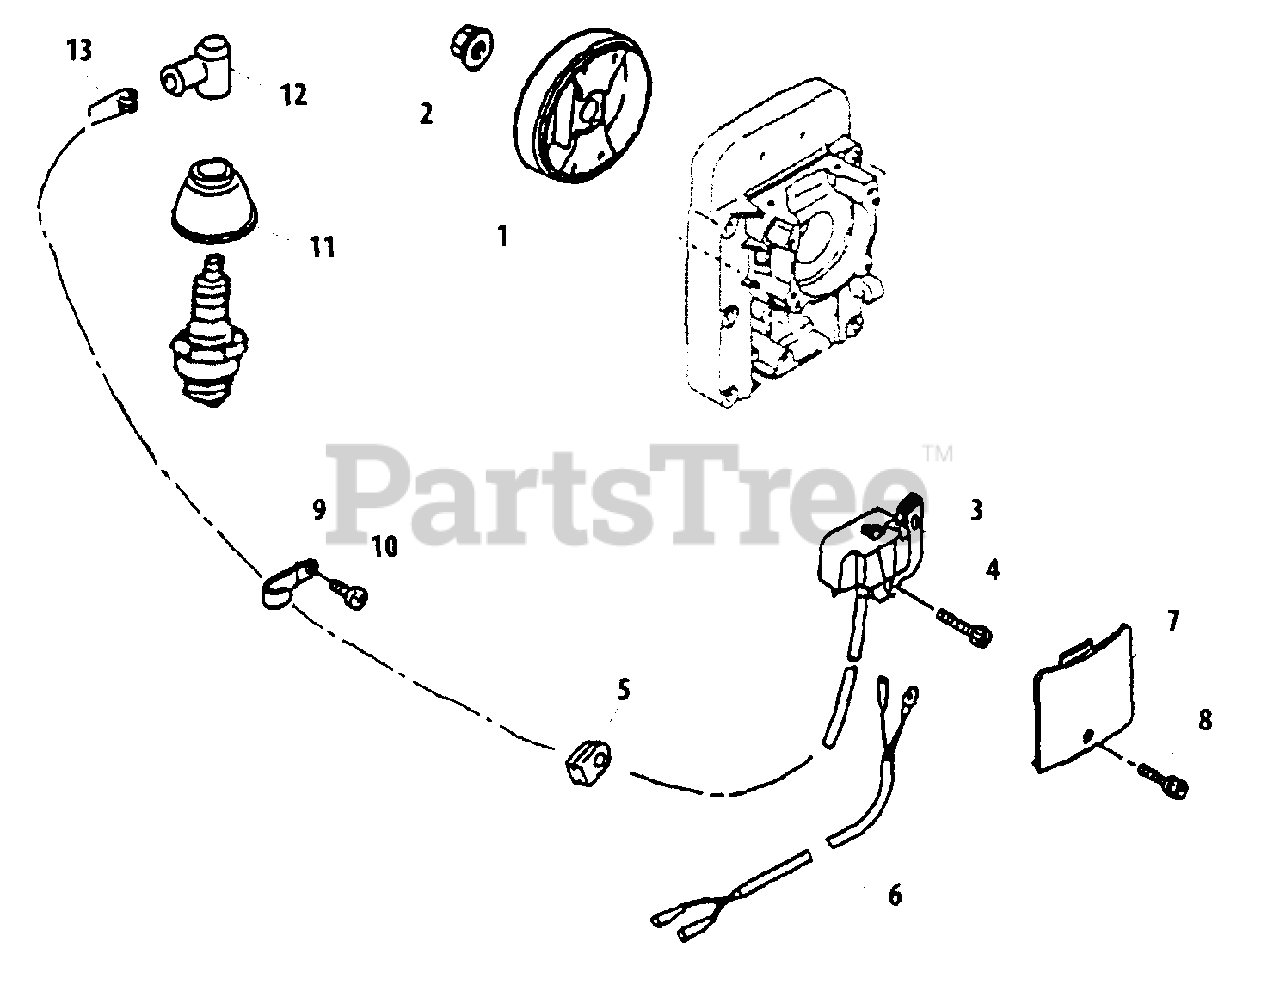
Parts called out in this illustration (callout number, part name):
1	FLYWHEEL
2	NUT, FLANGE M10
3	COIL, IGNITION
4	BOLT M4×20
5	GROMMET
6	LEAD - IGNITION
8	BOLT M4×16
9	CLIP
10	SCREW, TAPPING 5×14
11	COVER, SPARK PLUG
12	CAP, SPARK PLUG
13	TERMINAL
